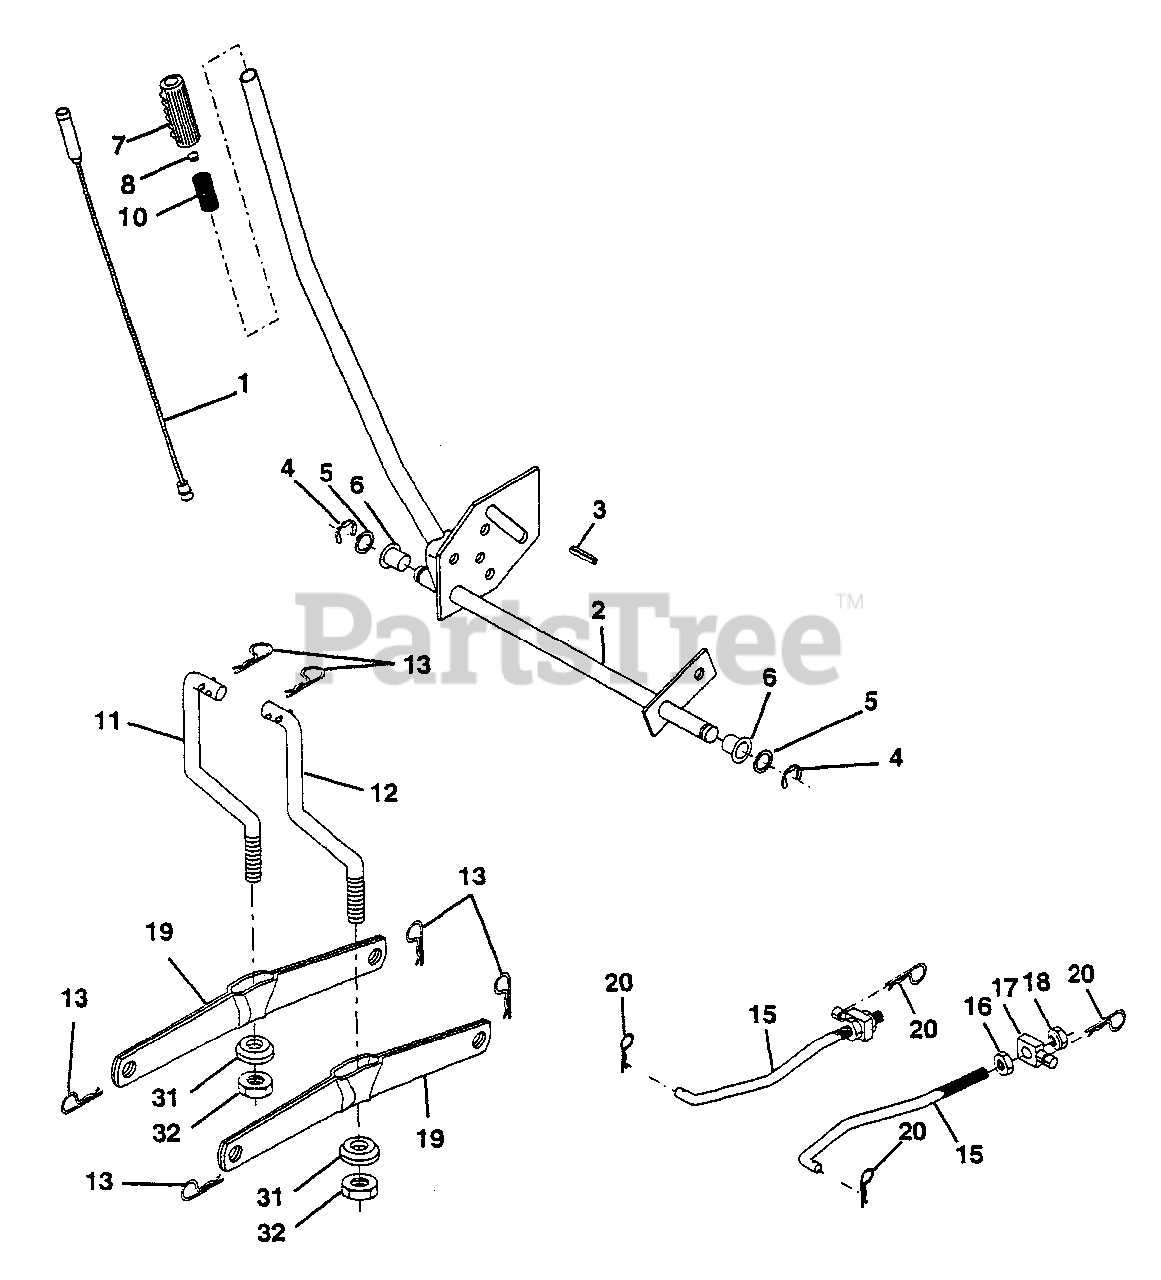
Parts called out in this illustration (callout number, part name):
1	Wire Asm Inner W/plunger 17 32
2	Shaft Asm Lift
3	Pin Groove
4	E Ring #5133-62
5	Washer PLTD 21/32 X 1 X 21ga
6	Bearing Nylon Blk 629 Id
7	Grip Handle Bicycle Matte Blk
8	Button Plunger Black
10	Spring Cprsn 3 750 Oiled
11	Link Lift LH
12	Link Lift RH
13	Retainer Spring
15	Link Front
16	Nut Jam Hex 1/2-13 Unc
17	Trunnion Blk Zinc
18	Nut Lock W/wsh 1/2-13unc
19	Arm Suspension Rear
20	Spring, Retainer
31	Bearing Pvt. Lift Spherical
32	Nut Lock 3/8-24 W/Nylon Insert
